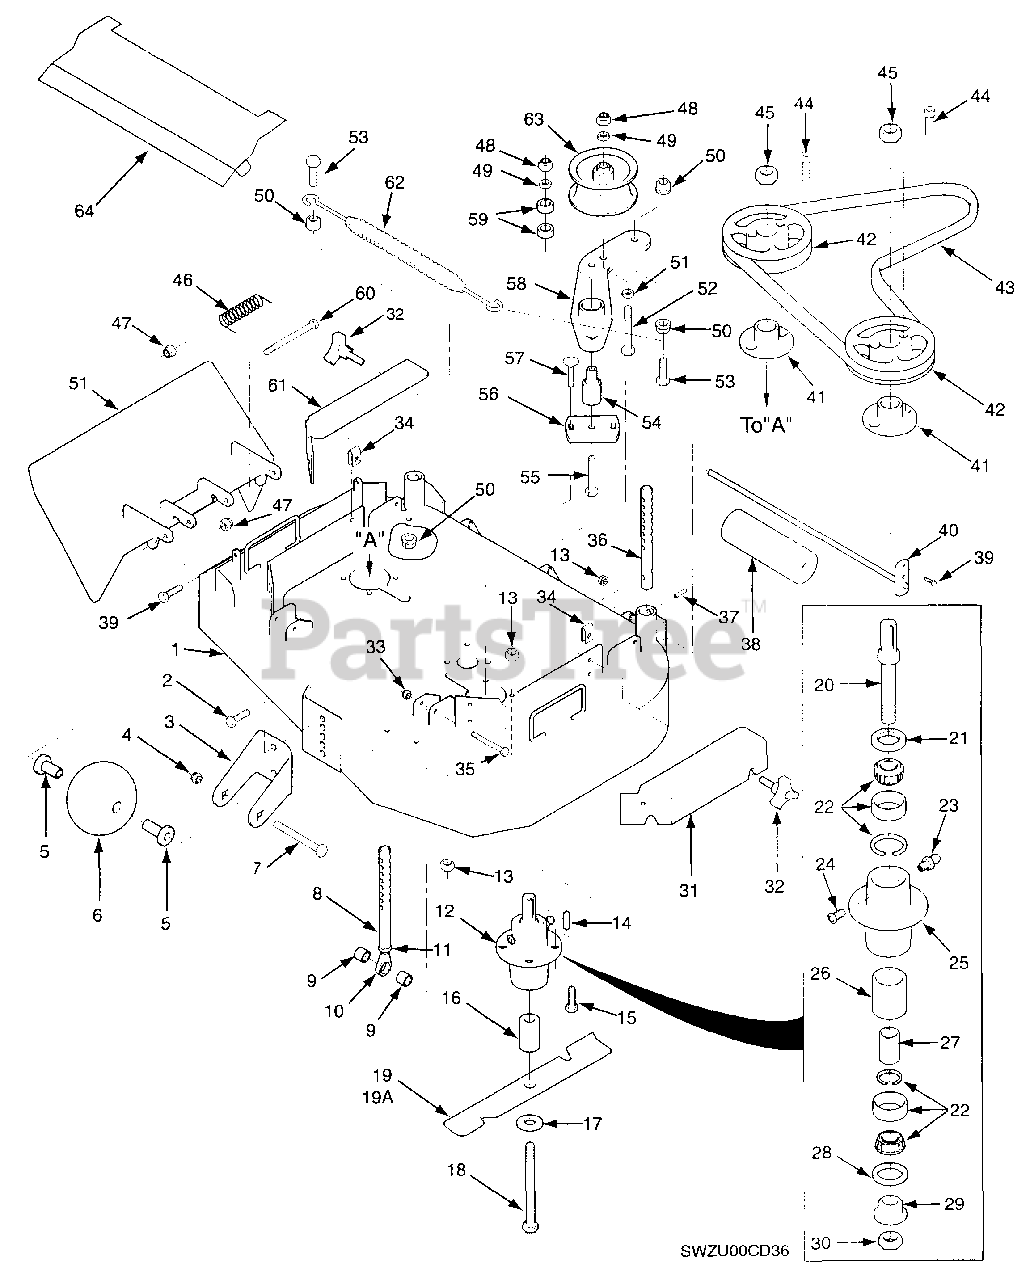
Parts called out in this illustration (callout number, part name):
1	Cutter Deck
2	Capscrew, 3/8-16 x 1.0" Serrated Flange Hex Hd
3	Bracket, Anti-Scalp Wheel
4	Lock Nut, 3/8-16 Center Lock
5	Bushing, 376 ID Oilite
6	Wheel, Anti-Scalp
7	Bolt, Carriage 3/8-16 x 4.0"
8	Pin Assy., Deck Adj.
9	Spacer, Deck Adjustment Pin
10	Rod End, Male 3/8-24 RH Thread
11	Nut, 3/8-24 Jam
12	Spindle Assembly
13	Nut, 5/16-18 Serrated Flange
14	Key, 1/4 x 1/4 x 2.0"
15	Bolt, Hex Head 5/16-18 x 1.25"
16	Spacer, Spindle
17	Flatwasher, 5/8 W
18	Bolt, Hex Head 5/8-11 x 9.50"
19	Cutter Blade 18" (marbane)
20	Spindle Shaft
21	Seal, Cutter Spindle Top
22	Tapered Bearing Set
23	Grease Fitting
24	Relief Fitting, Cutter Spindle
25	Spindle Housing
26	Spacer Outside
27	Spacer, Inside
28	Seal Cutter Spindle Bottom
29	Spindle Bushing
30	Nut Spindle
31	Belt Cove LH
32	Wing Nut. 3/8-16
33	Nut, 3/8-16 Elastic Stop
34	U-Nut, 3/8-16
35	Bolt, Hex Head 3/8-16 x 2.50"
36	Pin, Deck Adj. Rear
37	Pin, Sloted Spring 3/16 x 1.50"
38	Guide, Roller
39	Bolt, Hex Head 5/16-18 x 1.0"
40	Roller Shaft
41	Tapered Hub
42	Pulley
43	Belt, Cutter Deck
44	Capscrew, Socket Head. 1/4-20 x 1.375"
45	Hex Nut, 5/8-11
46	Spring, Chute Return
47	Hex Nut, 5/16-18 Elastic Stop
48	Hex Nut, 3/8-16 Elastic Stop
49	Flatwasher, 3/8 (.938 x .391 x .105)
50	Nut, 3/8-16 Serrated Flange
51	Discharge Chute
52	Capscrew, Hex Head 3/8-16 x 3.75"
53	Capscrew, Hex Head 3/8-16 x 1.50"
54	Pivot, Idler - Long
55	Capscrew, Hex Head 38/16 x 3.25"
56	Base, Idler Pivot
57	Bolt, Carriage 5/16-18 x 1.0"
58	Idler Arm Weldment
59	Ball Bearing
60	Bolt, Hex Head 5/16-18 x 4.25"
61	Belt Cover, RH
62	Spring, Deck Idler
63	Pulley, Idler
64	Heatshield
